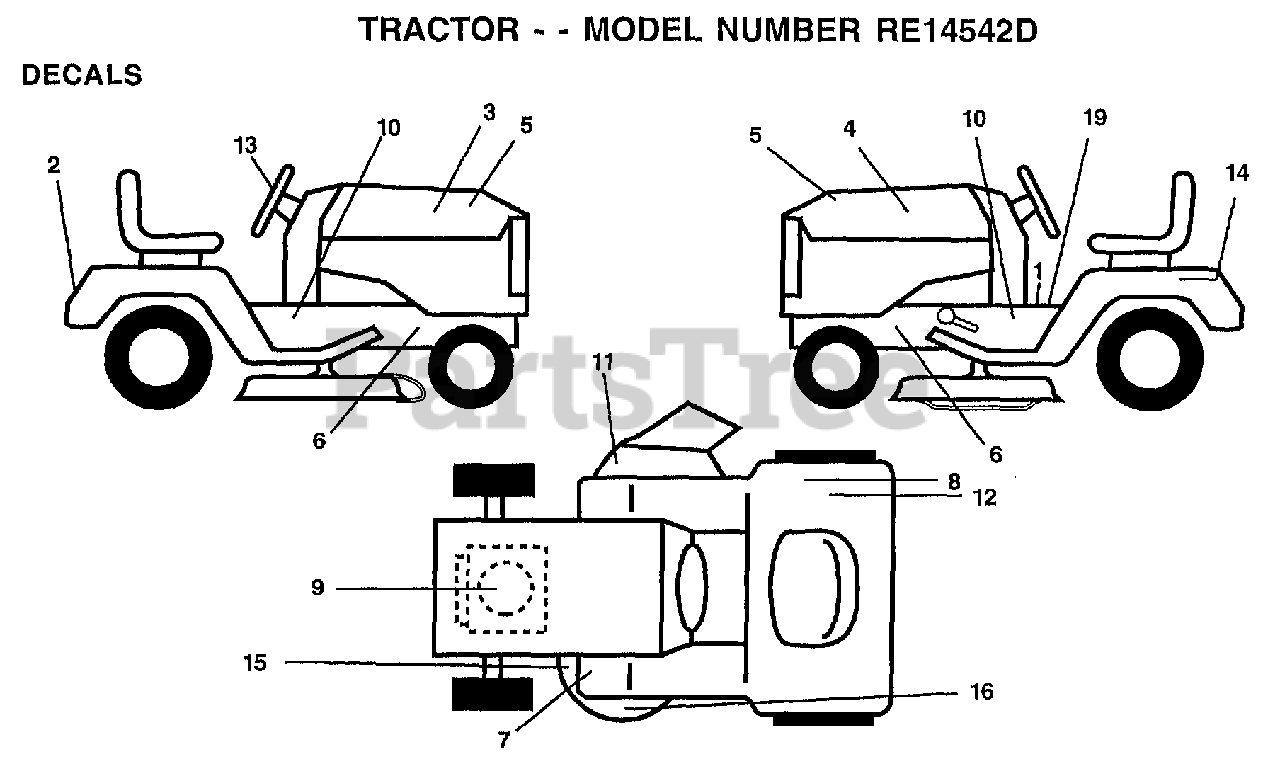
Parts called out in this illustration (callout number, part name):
1	DECAL.READ.O.MANU
2	FENDER DECAL
3	DECAL HOOD RH
4	DECAL HOOD LH
5	DECAL.INS.HD.RALL
6	"DECAL CHASSIS,HOT"
7	DECAL-BRAKE/CLUTC
8	DECAL.EURO.ST.CE.
9	DECAL, HP ENGINE
10	CHASSIS DECAL
11	DECAL.DANGER.CUTF
13	"DECAL,STR WHL"
14	DECAL.BATRY.3-3908
15	"DECAL-SCHEM,BELT"
19	DECAL BRAK PARK
